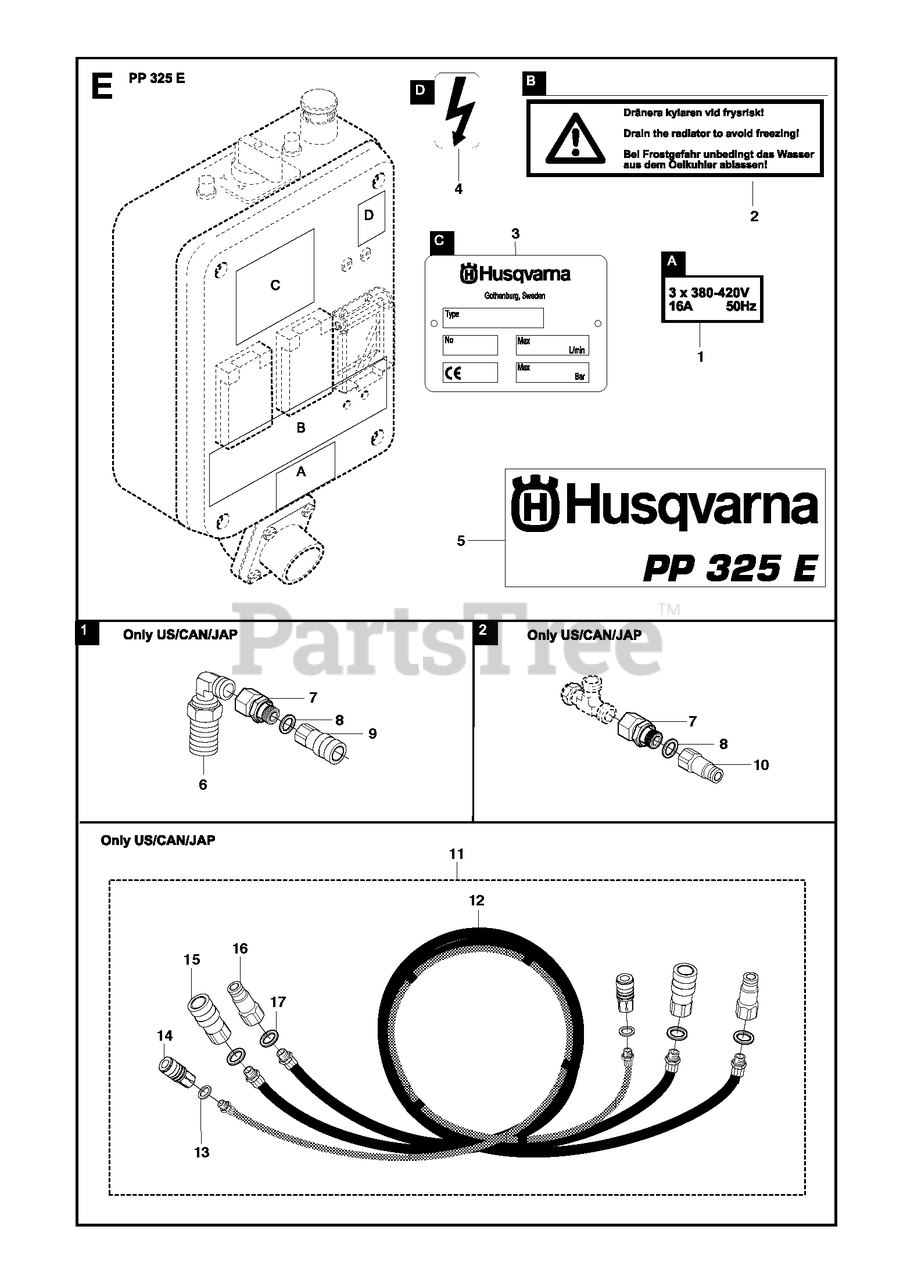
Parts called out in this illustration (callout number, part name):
6	SWIVELOnly US/CAN/JAP
7	CLUTCHOnly US/CAN/JAP
8	SEALING RINGOnly US/CAN/JAP
9	QUICK COUPLINGOnly US/CAN/JAP
10	QUICK COUPLINGOnly US/CAN/JAP
11	HOSE KITOnly US/CAN/JAP
